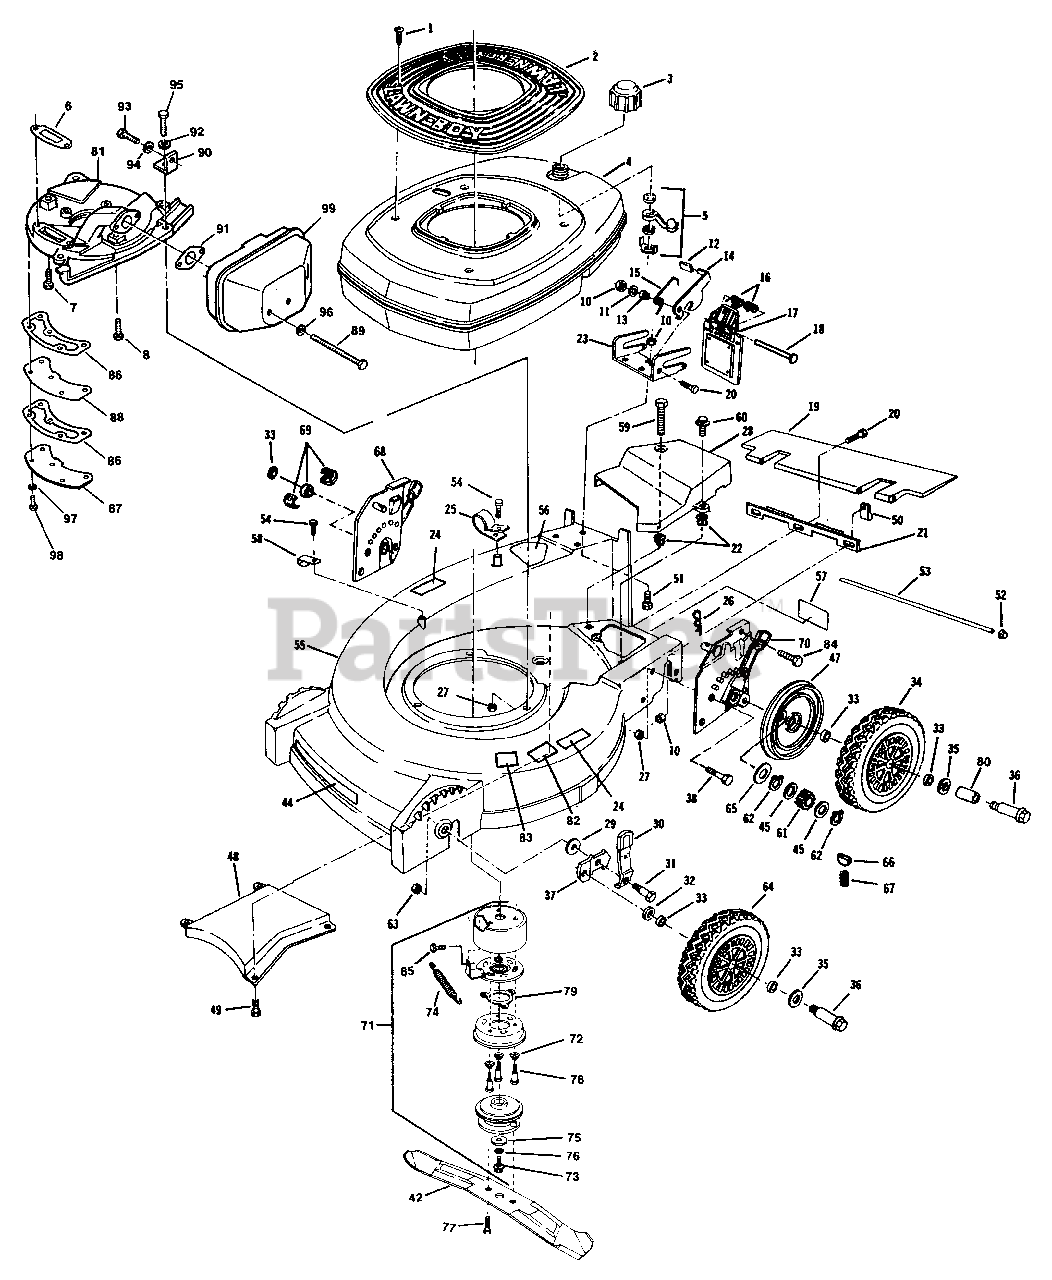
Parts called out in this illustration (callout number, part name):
1	Screw
2	Cover-Shroud
3	Fuel Cap
4	Shroud-Engine
5	Fuel Shut-Off Assemby
6	Gasket-Exhaust
7	Screw-Muffler to Block
8	Screw-Muffler Plate to Block
9	Screw-Muffler Plate to Housing
10	Nut-Latch Brk't. and Trailing Shield
11	Washer
12	Knob-Latch
13	Stepped Spacer
14	Catch-Bag
15	Spring-Latch
16	Spring
17	Door
18	Rod
19	Shield-Trailing
20	Screw-Latch Bracket and Trailing Shield
21	Bracket-Bag Hanger
22	Grommet
23	Hinge Plate
24	Decal-Ht. Adj.
25	Clamp-Cable and Primer Hose to Housing
26	Pin
27	Nut-Ht. Adj. to Hous. and Muff. Plate to Hous.
28	Cover Belt
29	Washer-Wheel Ht. Adj.
30	Knob and Spring Assembly
31	Bolt-Shoulder
32	Washer
33	Washer-Felt
34	Wheel and Tire Assembly 8" S.P.
35	Washer-Wheel Bolt
36	Bolt-Shoulder Wheel
37	Bracket-Wheel Ht. Adj.
38	Bolt-Height Adjuster Assembly
42	Blade-20"
44	Decal-Clutch
45	Spacer
47	Cover-Wheel
48	Baffle
49	Screw
50	Clamp-Rod
51	Screw-Truss Head
52	Nut-Rod
53	Rod-Trailing Shield
54	Screw-Clamp to Housing
55	Housing-20" Assembly
56	Decal-Blade Contact Warning
57	Decal-Caution
58	Clamp-Cable to Housing
59	Screw-Hex Hd.
60	Screw-Shoulder Idler
61	Pinion
62	Retaining Ring
63	Nut-Wheel Ht. Adj.
64	Wheel and Tire Assembly 8"
65	Washer
66	Key
67	Spring
68	Height Adjuster Assem.-R.H.
69	Bearing and Retainer Ass'y.
70	Height Adjuster Assem.-LH.
71	Clutch Assembly
72	Spring
73	Screw
74	Spring
75	Washer
76	Lockwasher
77	Screw
78	Screw
79	Gasket
80	Bushing
81	Mounting Plate
82	Starting Pad
83	Decal
84	Bolt
85	Bolt-Cable to Arm
86	Gasket-Muffler
87	Cover Gasket
88	Baffle
89	Screw
90	Bracket-Muffler
91	Gasket-Muffler
92	Washer
93	Screw
94	Washer
95	Bolt
96	Washer
97	Lockwasher
98	Screw
99	Muffler
